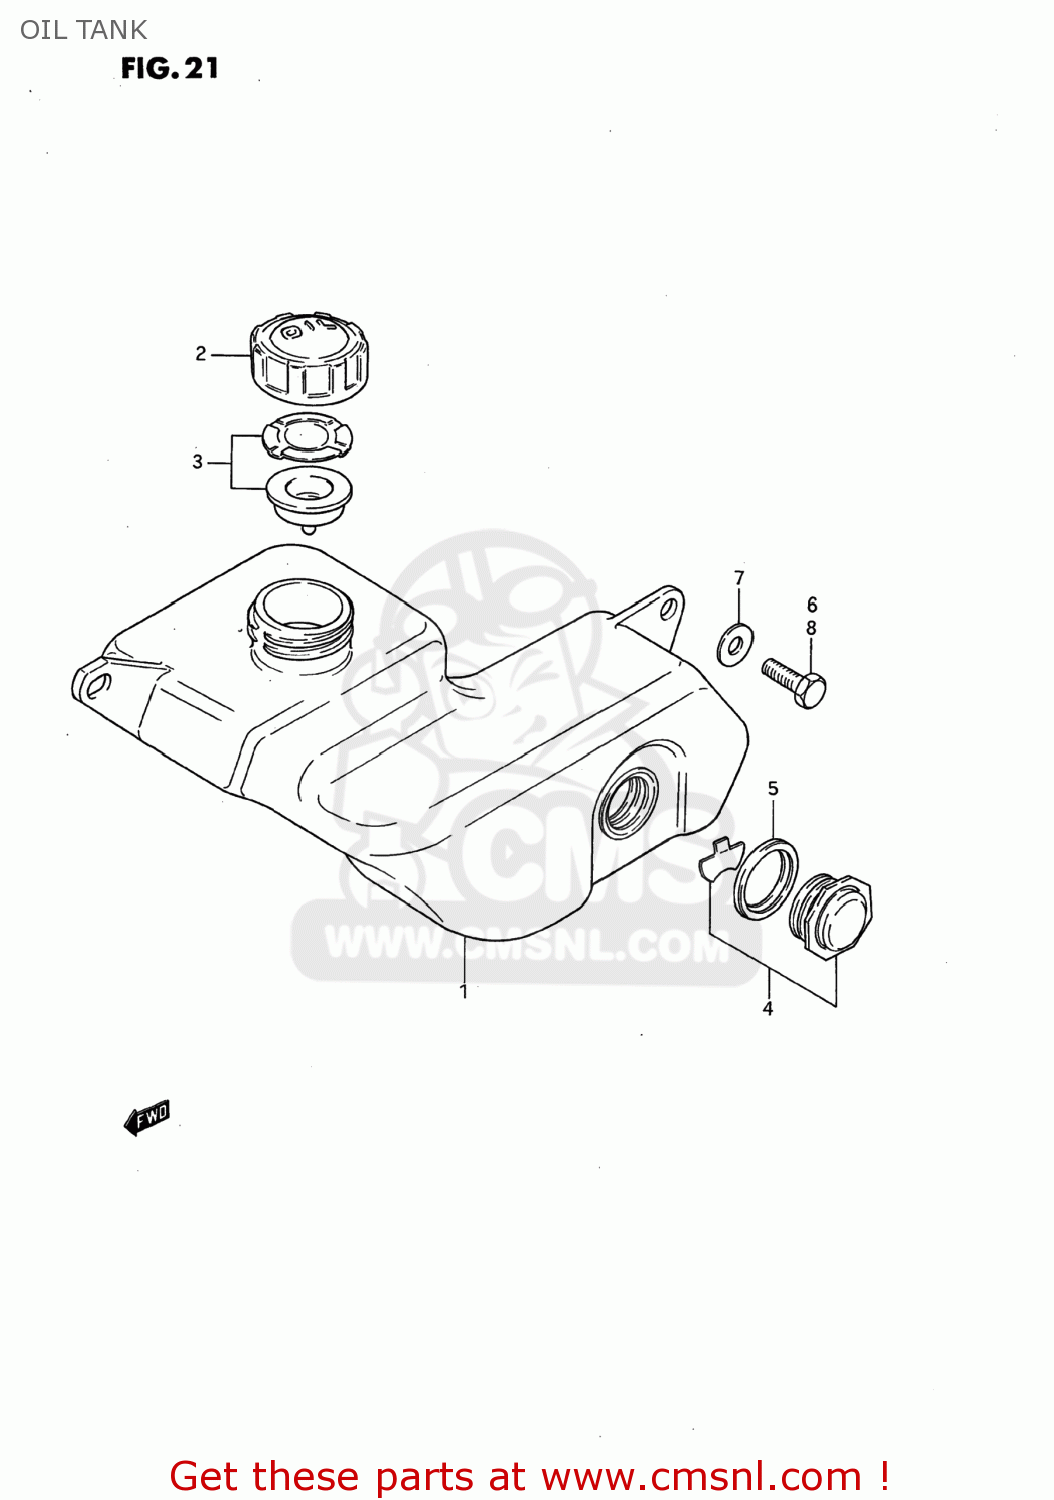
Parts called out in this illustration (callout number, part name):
1	TANK,OIL
2	CAP,OIL TANK
3	GASKET SET (NAS)
4	LENS SET,OIL LEVEL
5	GASKET (NAS)
6	BOLT
7	WASHER
8	BOLT(6X16)
